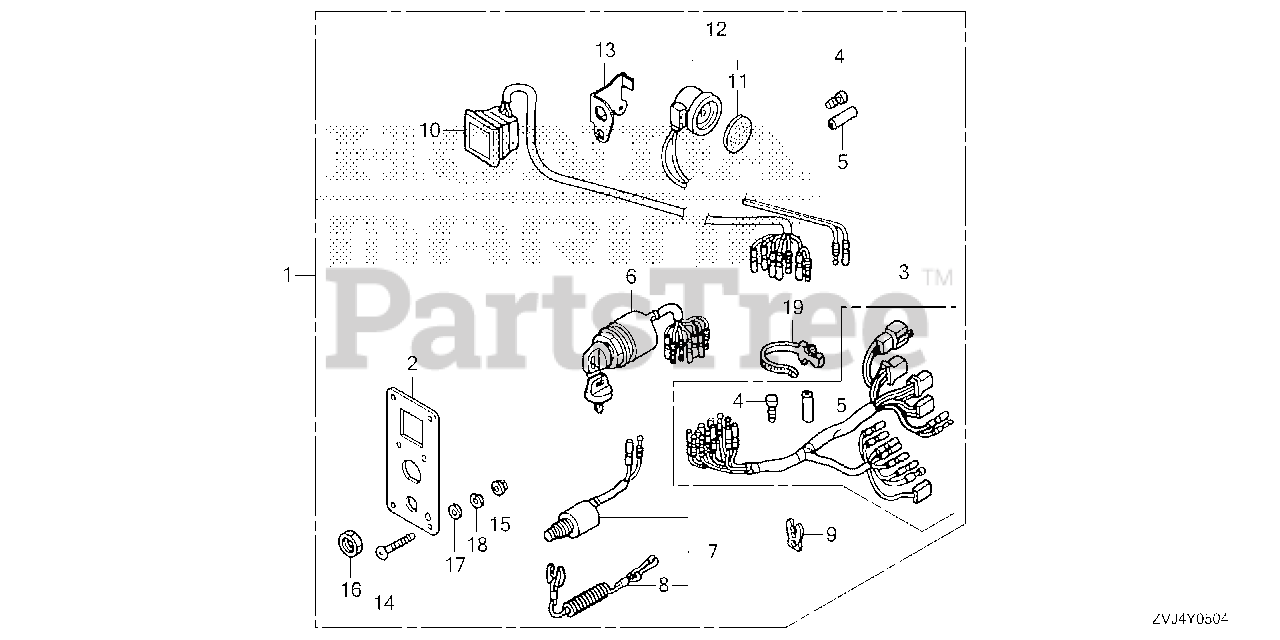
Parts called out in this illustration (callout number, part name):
1	PANEL KIT, SWITCH (4-LED)
2	PANEL, CONTROL
3	HARNESS ASSY., SWITCH PANEL
4	PLUG, CONNECTOR (INNER)
5	PLUG, CONNECTOR (OUTER)
6	SWITCH ASSY., COMBINATION
7	SWITCH ASSY., EMERGENCY STOP
8	WIRE, EMERGENCY
9	CLIP, EMERGENCY LOCK
10	LAMP ASSY., INDICATION (4-LED)
11	PLATE, TURN SIGNAL BUZZER
12	BUZZER, WARNING
13	BRACKET, BUZZER
14	SCREW, PAN (5X40)
15	NUT, FLANGE (5MM)
16	NUT, HEX. (16MM)
17	WASHER, PLAIN (5MM)
18	WASHER, SPRING (5MM)
19	BAND, WIRE HARNESS (150MM) (NATURAL)
